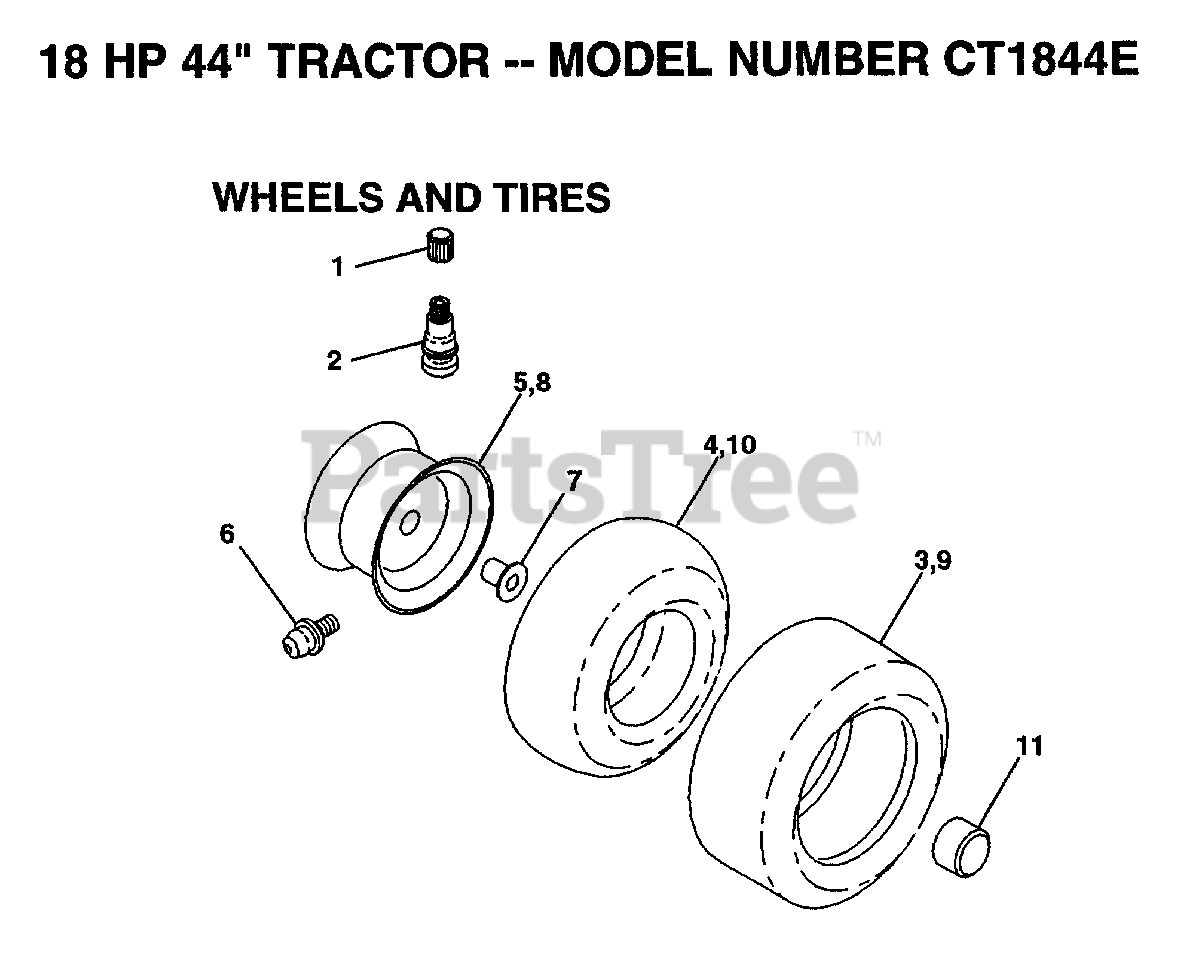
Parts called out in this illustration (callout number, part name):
1	VALVE CAP
2	VALVE STEM LT
4	TUBE.5.3/4.5/6
6	FITTING LT
7	"FLANGE, BEARING"
10	TUBE.18X9.5-8
11	HUB CAP
